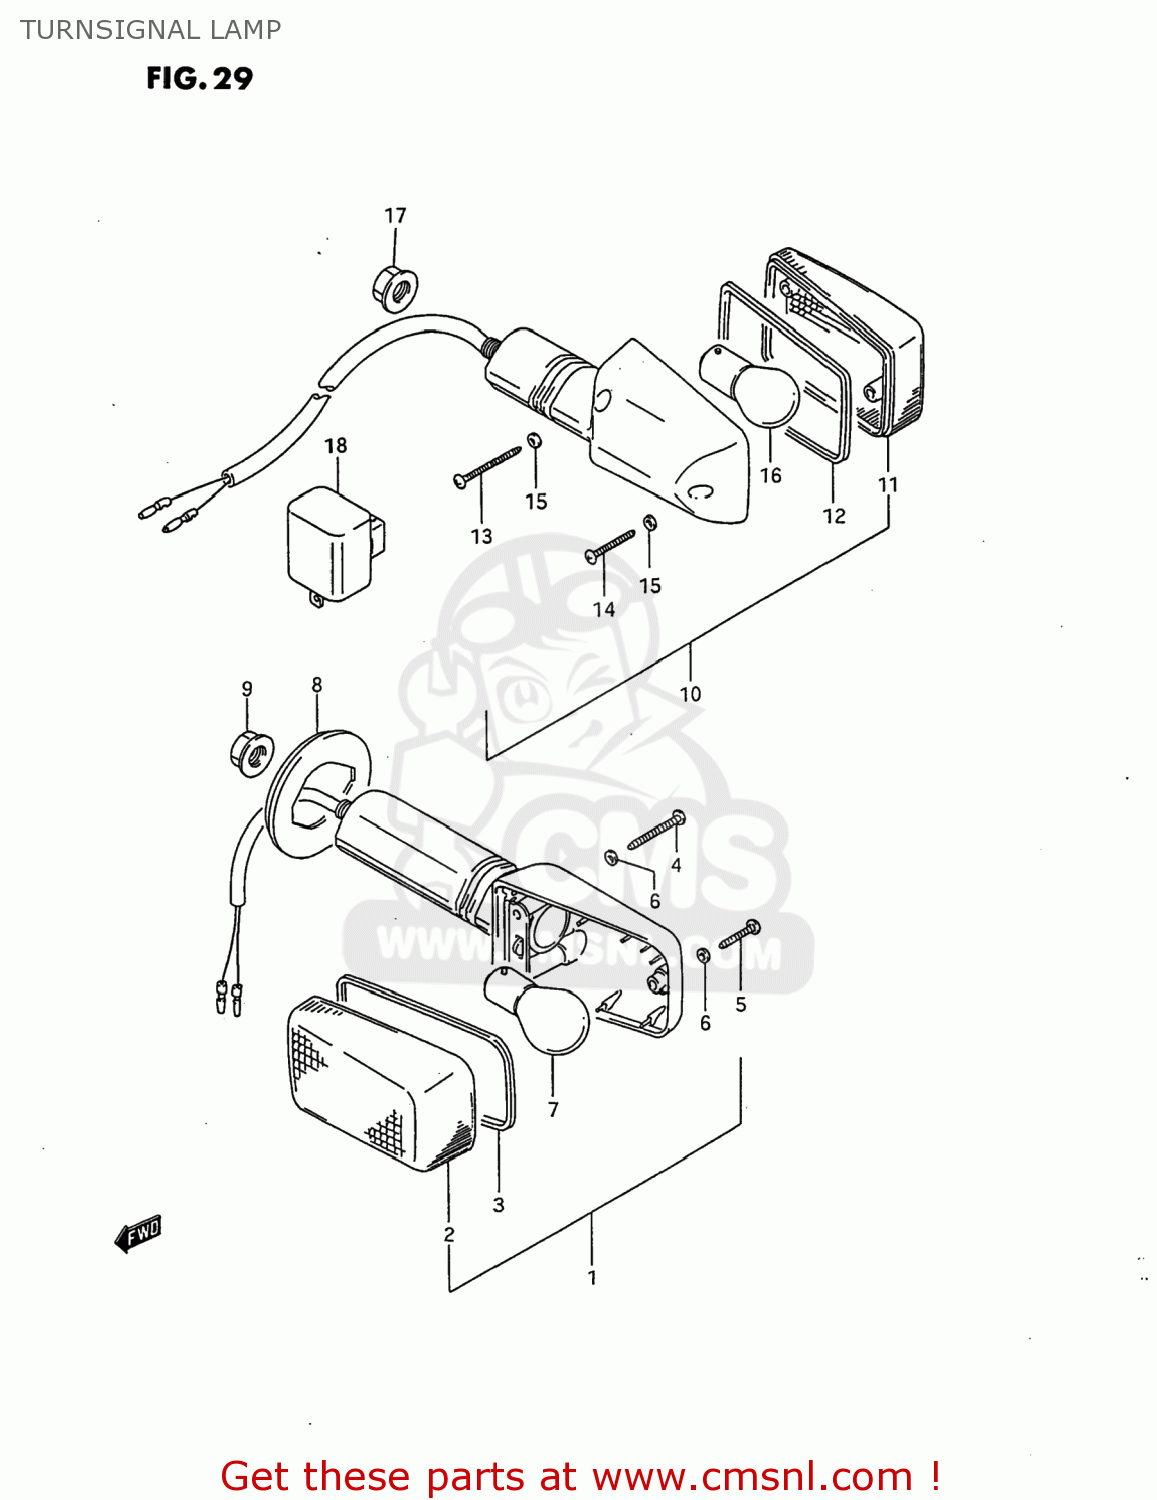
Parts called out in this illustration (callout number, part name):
1	LAMP ASSY,FR TURN SIGNAL
2	LENS
3	GASKET (NAS)
4	SCREW(3X30)
5	SCREW
6	GASKET (NAS)
7	BULB(12V21W)
8	GROMMET
9	NUT
10	LAMP ASSY,RR TURNSIGNAL
11	LENS
12	GASKET (NAS)
13	SCREW(3X30)
14	SCREW
15	GASKET (NAS)
16	BULB(12V21W)
17	NUT
18	RELAY ASSY,TURNSIGNAL LAMP
